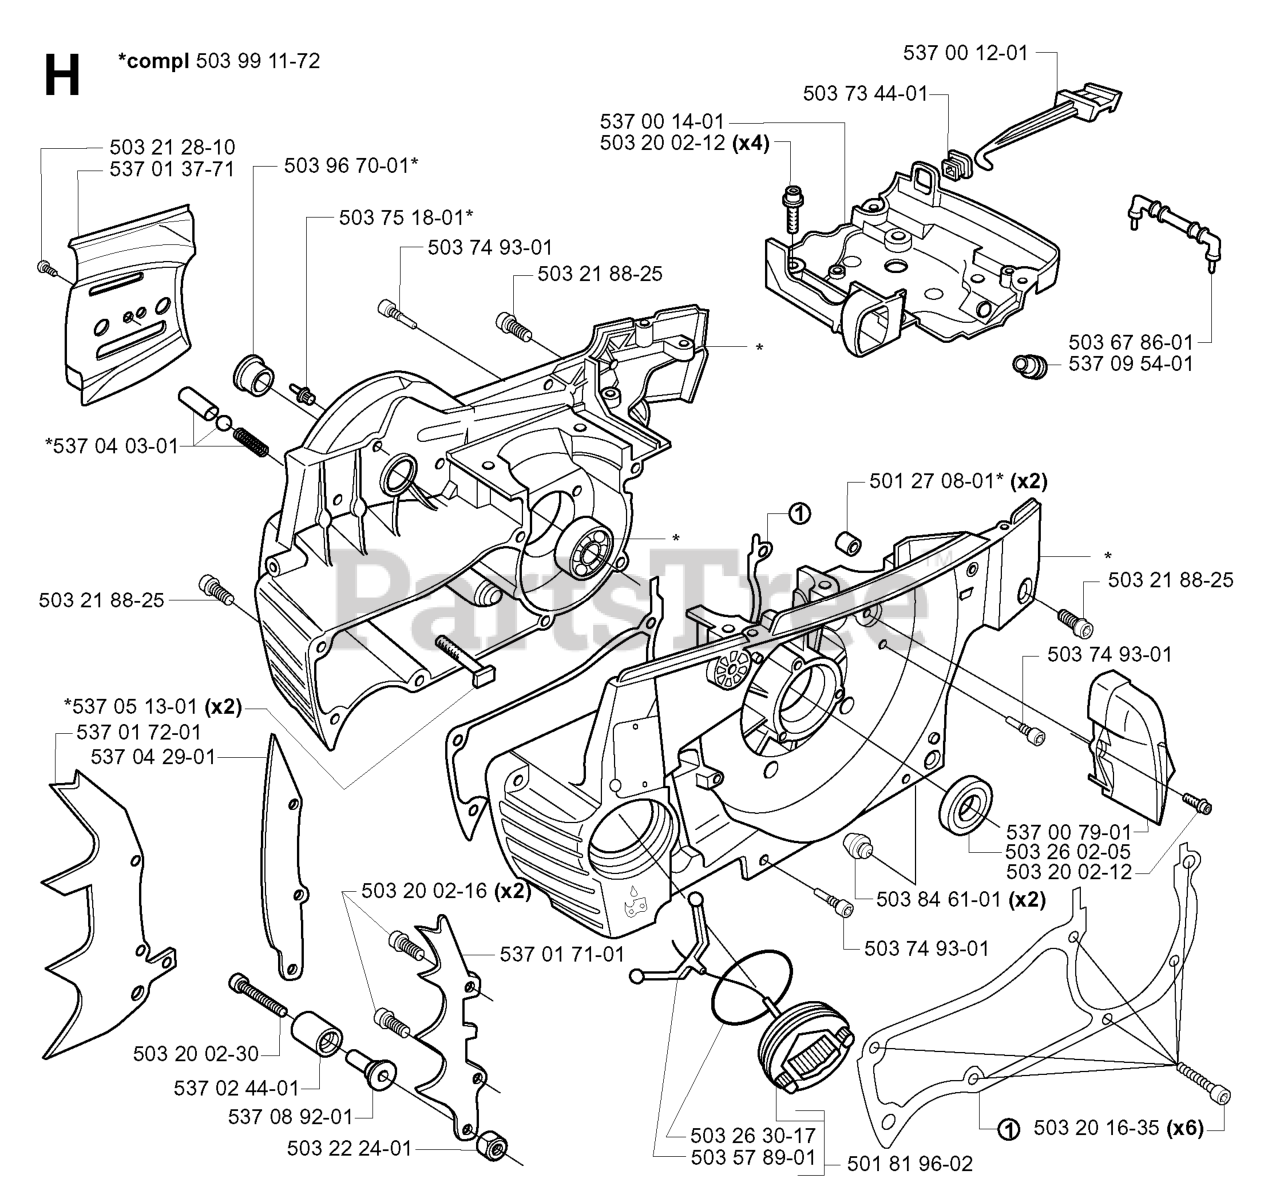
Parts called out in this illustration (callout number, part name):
1	DECAL.AUGER.SAFETY.
3	DECAL.CHUTE.SAFETY.
4	DECAL.AUGER."
6	DECAL.CONSOLE.INSTRUCTION
10	DECAL.REM.DEFLECTOR.LT
12	DECAL.BELT.GUARD.
14	DECAL.FENDER
15	DECAL, HUSQVARNA
